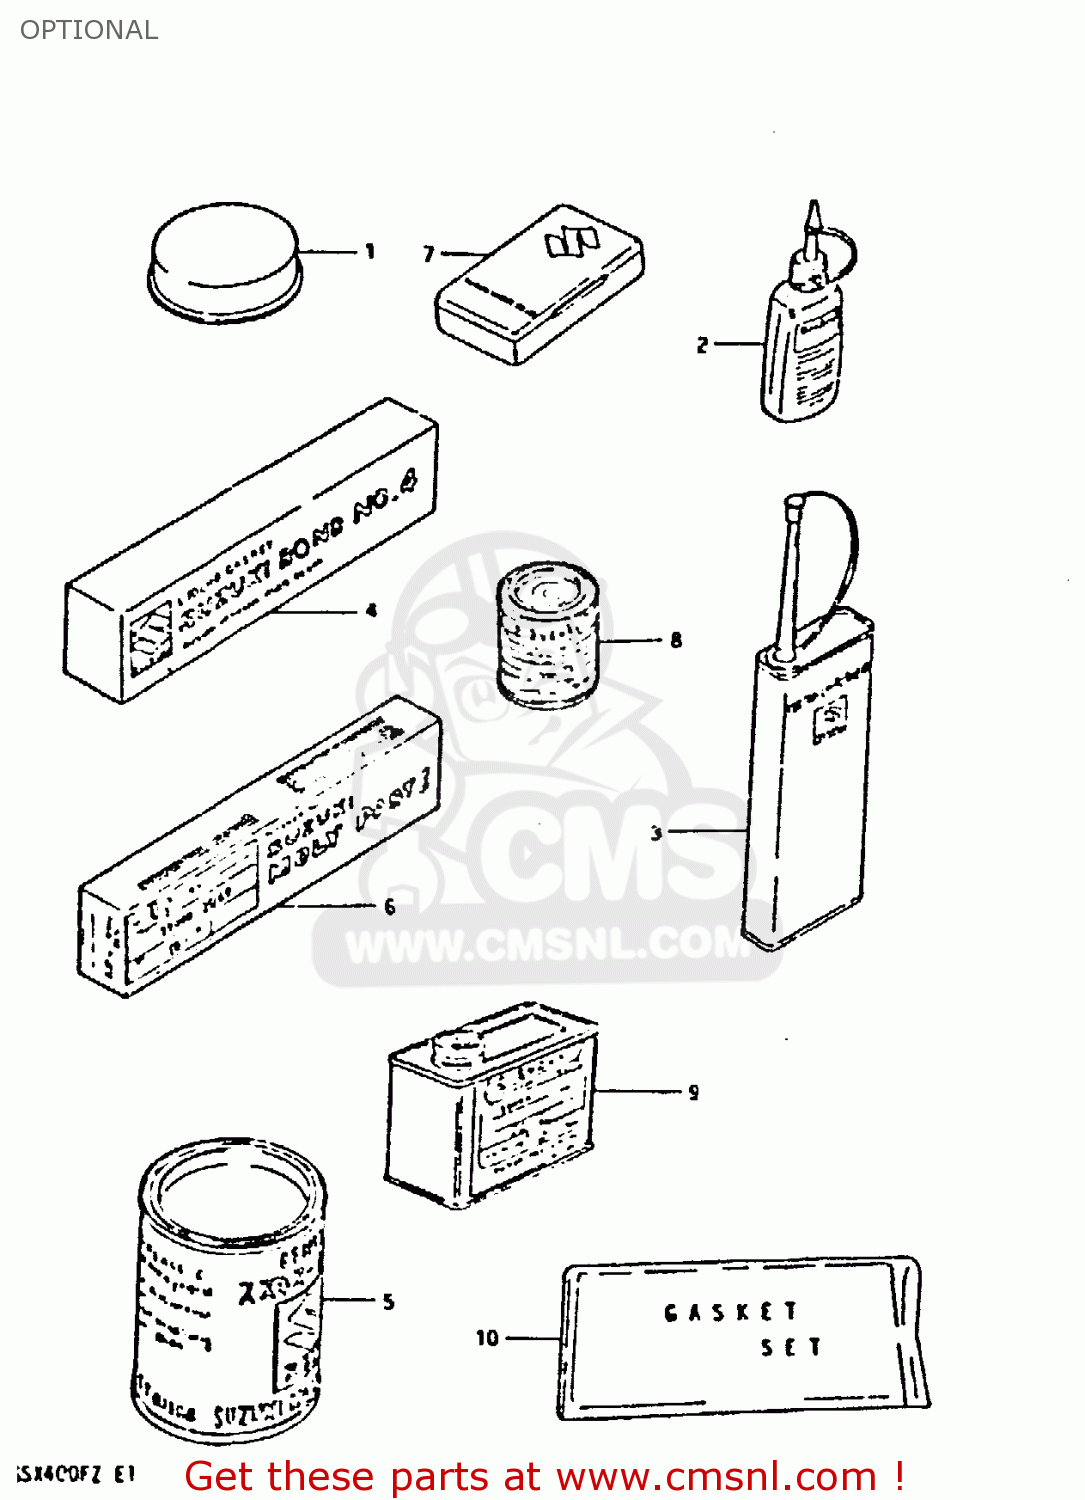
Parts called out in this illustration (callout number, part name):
1	GREASE,PBC FOR BRK PAD 20G
2	THREAD LOCK SUPER (1332B)
3	THREAD LOCK NO.1401 CLEAR 200G
4	BOND 1104
5	GREASE(C)EP2 LITHIUM 150G
6	SUZUKI MOLY PASTE
7	TUBE REPARING TOOL
8	PAINT,BLACK
9	PAINT (BLACK)
10	GASKET SET (MCA)
